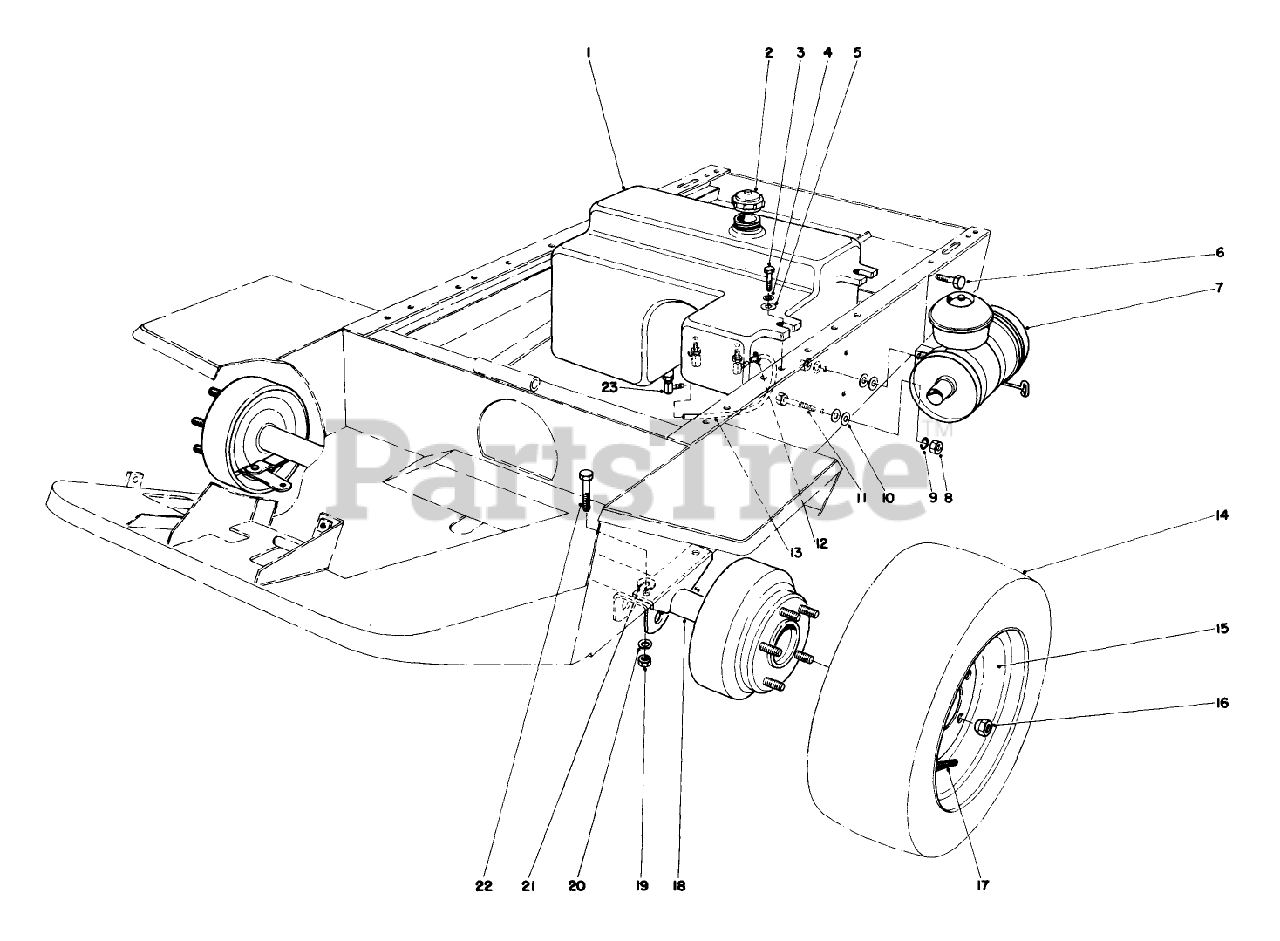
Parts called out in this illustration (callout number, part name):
1	Gas Tank
2	GAS CAP
4	WASHER-LOCK
5	WASHER-FLAT
6	SCREW-HH
7	Air Cleaner Assembly
8	NUT-HEX
9	WASHER-LOCK
10	WASHER-PLAIN
11	SCREW-HH
12	CLAMP-HOSE
13	HOSE-FUEL
14	Tire
15	WHEEL ASM
16	NUT-WHEEL
17	VALVE STEM AND CAP ASM
19	NUT-HEX
20	WASHER-LOCK
21	SPECIAL WASHER
22	SCREW-HH
23	FITTING-ELBOW, 90 DEG
